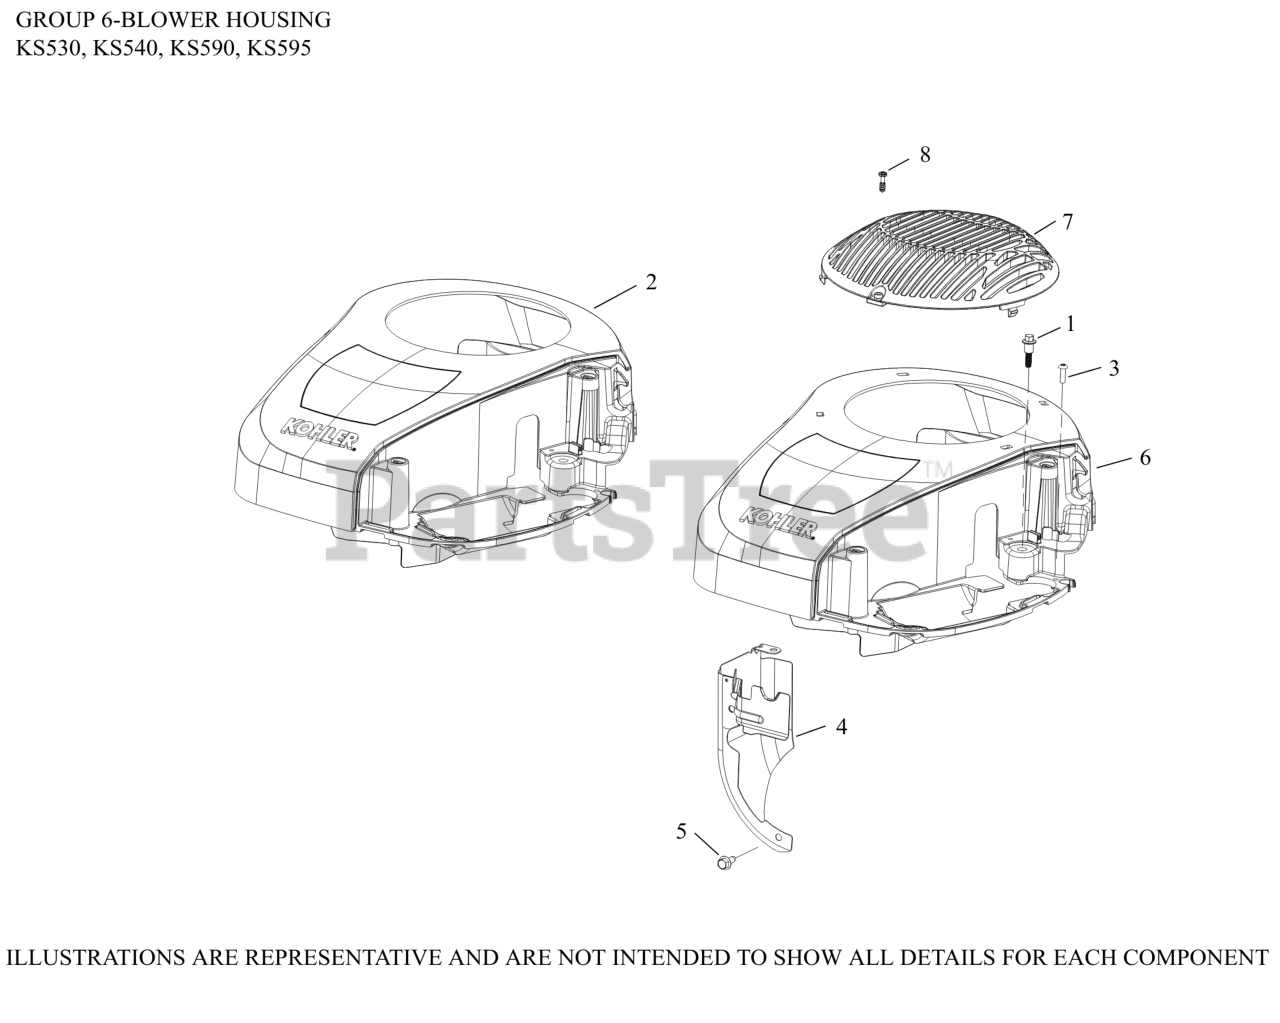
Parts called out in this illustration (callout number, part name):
1	SCREW, SHD THD FRM M6X1X26
2	KIT, BLOWER HOUSING
3	SCREW, HI-LOW
4	BAFFLE, BARREL ASSY
5	SCREW, THREAD FORMING
